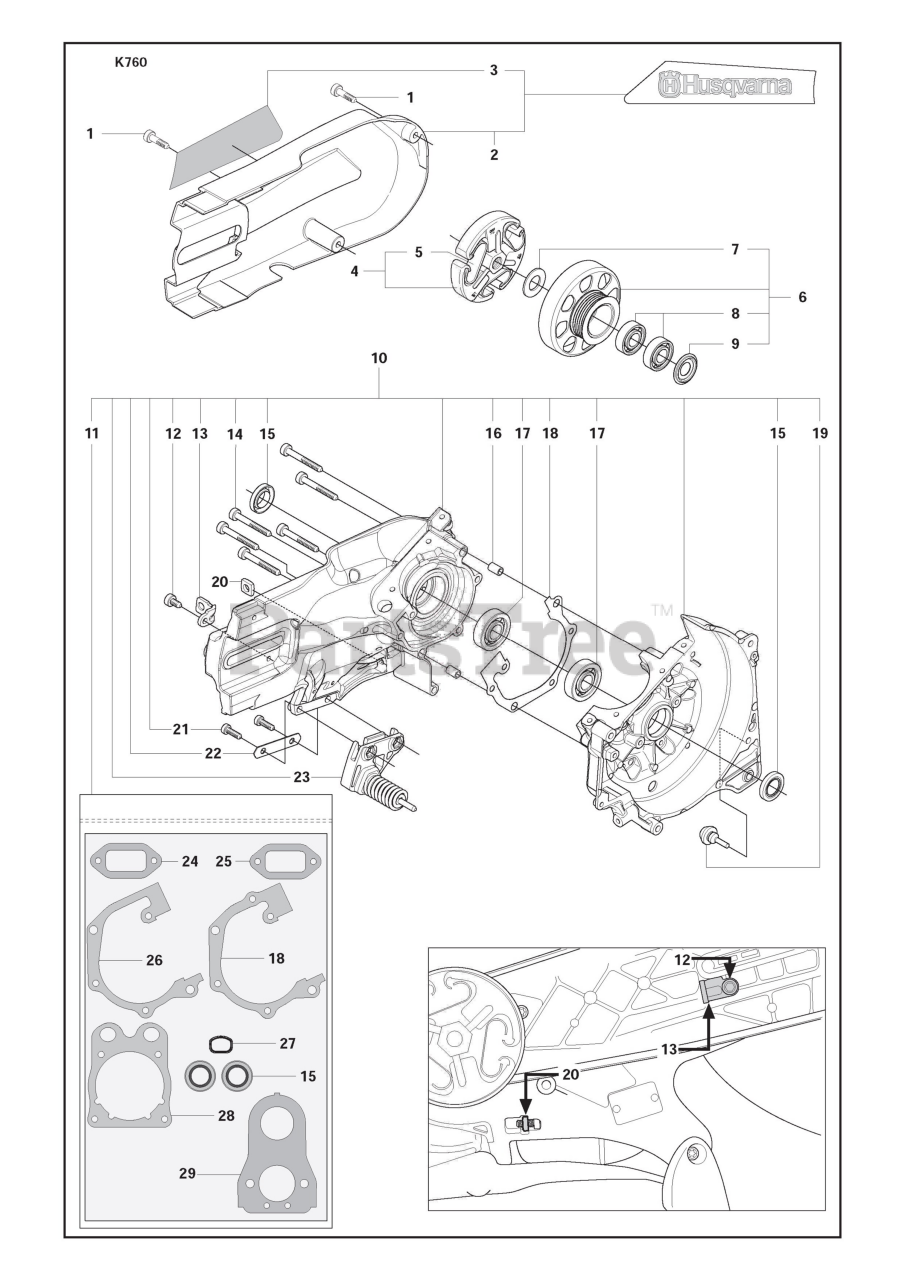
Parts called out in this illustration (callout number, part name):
2	Belt Guard
4	Clutch Assy
5	Clutch Spring
6	Driving Pulley Assy
7	Washer Steel
8	Ball Bearing
9	Dust Cover
10	Crankcase Assy
11	Gasket Kit
15	Sealing Ring
16	Guide Bushing
17	Ball Bearing
18	Gasket Crankcase
23	Spring Retainer
25	Gasket Muffler
26	Gasket Crankcase
28	Cylinder Base Gasket
29	Gasket Carburettor
